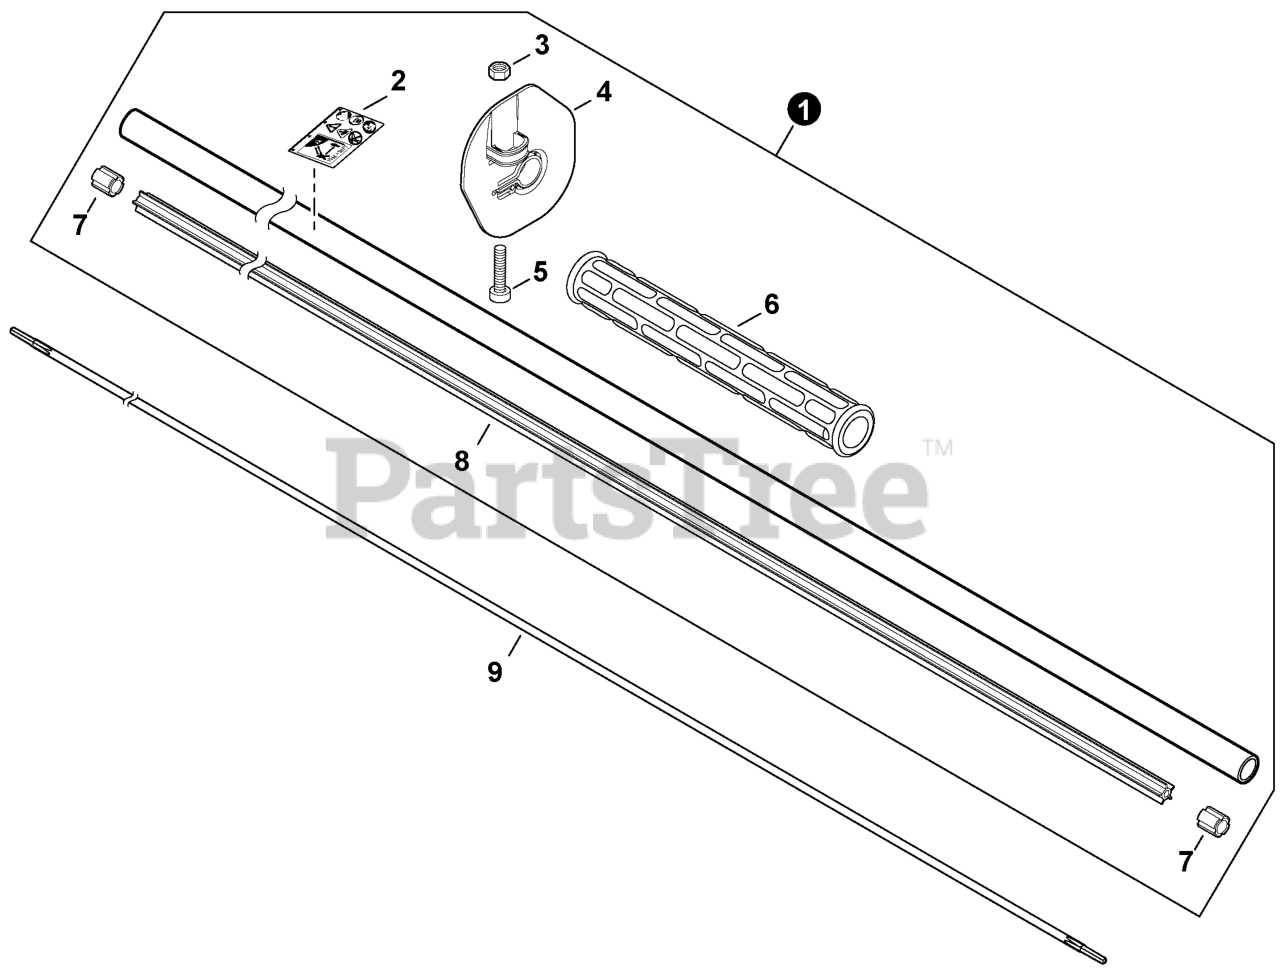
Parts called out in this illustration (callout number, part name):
1	MAIN PIPE ASSY
2	LABEL - CAUTION
4	GUARD, HAND
5	BOLT, TORX 5x20
6	GRIP, FRONT
8	LINER, FLEXIBLE 21.6x1420
9	DRIVESHAFT - FLEXIBLE
